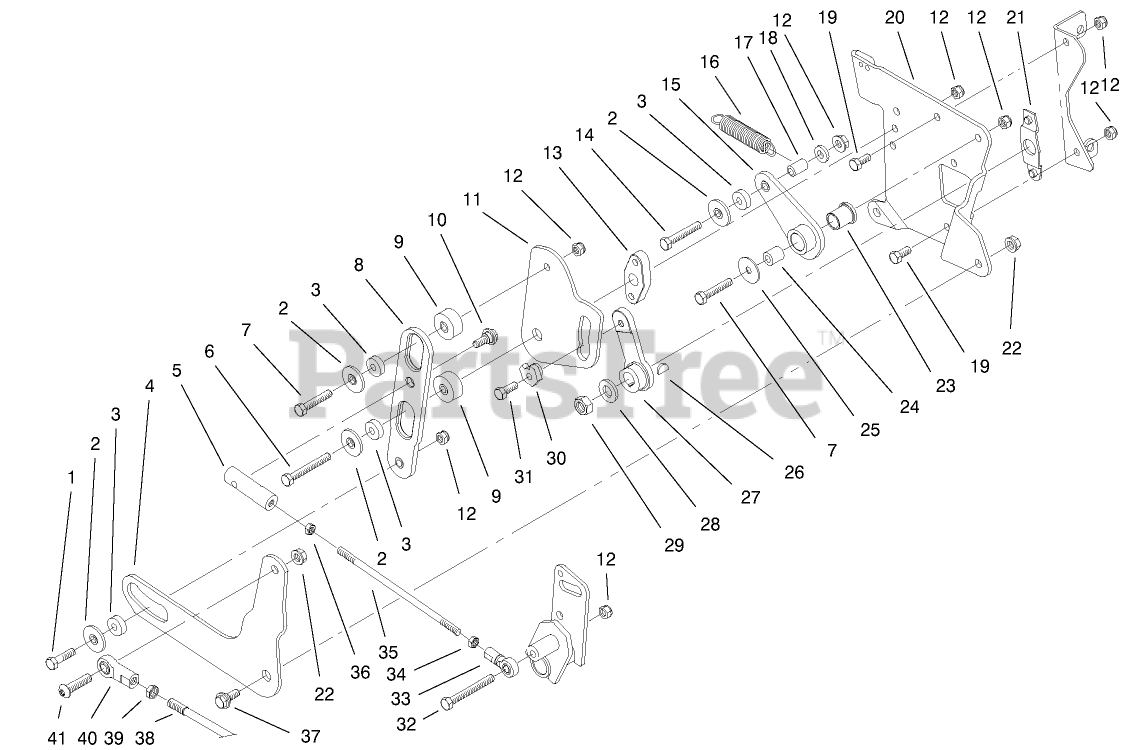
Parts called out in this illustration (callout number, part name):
1	SCREW-HH
2	RETAINER-BEARING
3	BEARING-BALL
4	SLIDER-LIFT
5	END-ROD, RH
6	SCREW-HH
7	SCREW-HH
8	SLIDER-CONTROL, SPEED
9	STANDOFF-CAM PLATE
10	BOLT-SHOULDER
11	PLATE-CAM
12	NUT-LOCK, NI
13	STANDOFF-SLIDER
14	SCREW-HH
15	ARM-RETURN TO NEUTRAL
16	SPRING-IDLER
17	STANDOFF-SPRING
18	WASHER-PLAIN
19	SCREW-HH
20	PLATE-CONTROL
21	LOCATOR-CONTROL PLATE
22	NUT-HEX
23	BUSHING-FLANGED
24	SPACER
25	WASHER-FLAT
26	KEY-WOODRUFF
27	ARM-CONTROL, SPEED
28	WASHER-FLAT
29	NUT-HEX
31	SCREW-THREAD LOCKING
32	SCREW-HH
33	END-ROD, RH
34	NUT-JAM
35	ROD-SLIDER TO PIVOT
36	NUT-JAM
37	BOLT-SHOULDER
38	ROD-LIFT
39	NUT-HJ
40	END-ROD, FEMALE
41	SCREW-HSBH
